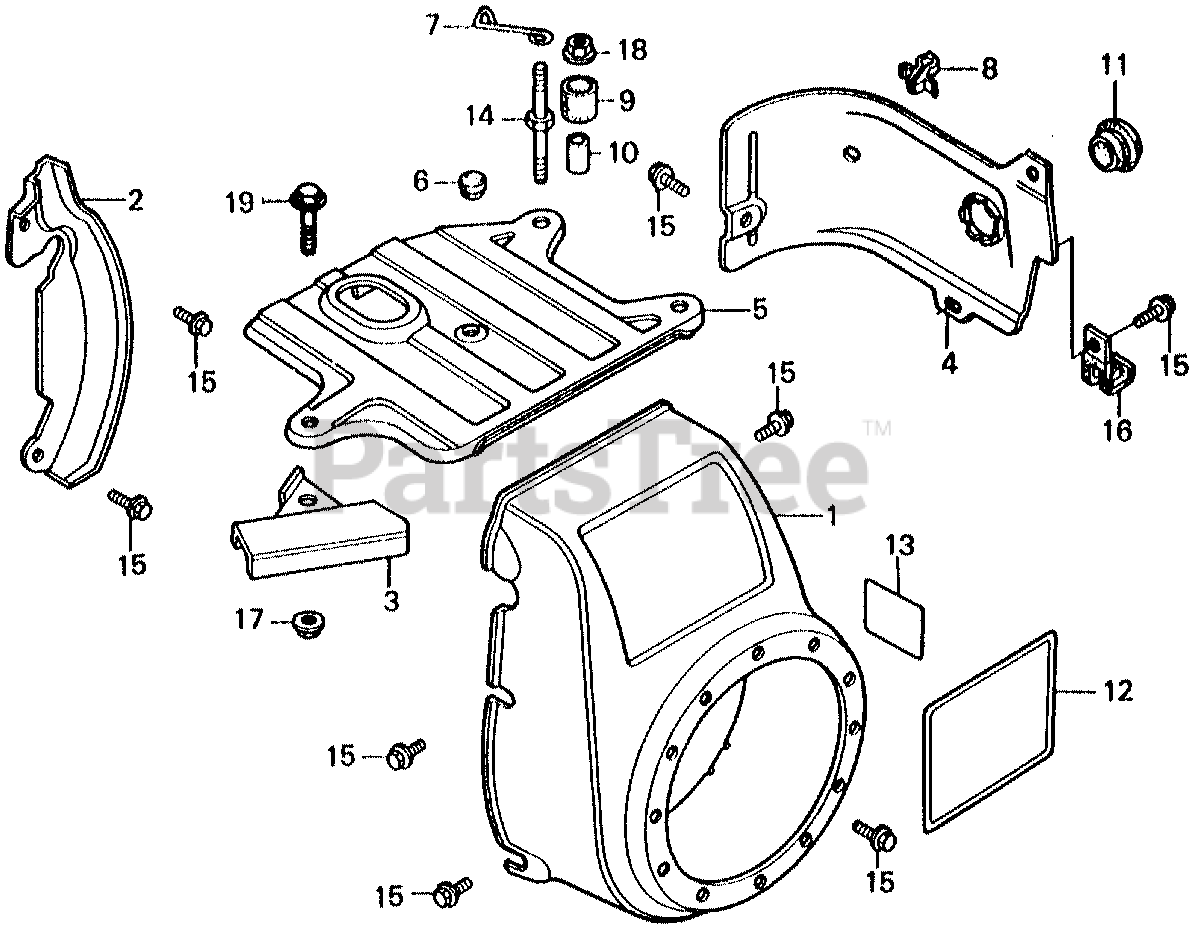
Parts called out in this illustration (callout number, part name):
1	COVER, FAN *R8* (BRIGHT RED)
2	PLATE, SIDE
3	GUIDE, AIR
5	COVER, TOP
6	GROMMET, TOP COVER
7	CLAMP, IGNITION WIRE
8	CLIP, IGNITION WIRE (8MM)
9	RUBBER, STOPPER (NOT AVAILABLE)
10	COLLAR, DISTANCE
11	GROMMET, DRAIN HOLE
12	EMBLEM (NOT AVAILABLE)
13	MARK, OIL CAUTION
14	BOLT, SPECIAL (NOT AVAILABLE)
15	BOLT, FLANGE (6X12) (CT200)
16	CLIP, CABLE
17	NUT, FLANGE (6MM)
18	NUT, FLANGE (8MM)
19	BOLT, FLANGE (6X28)
